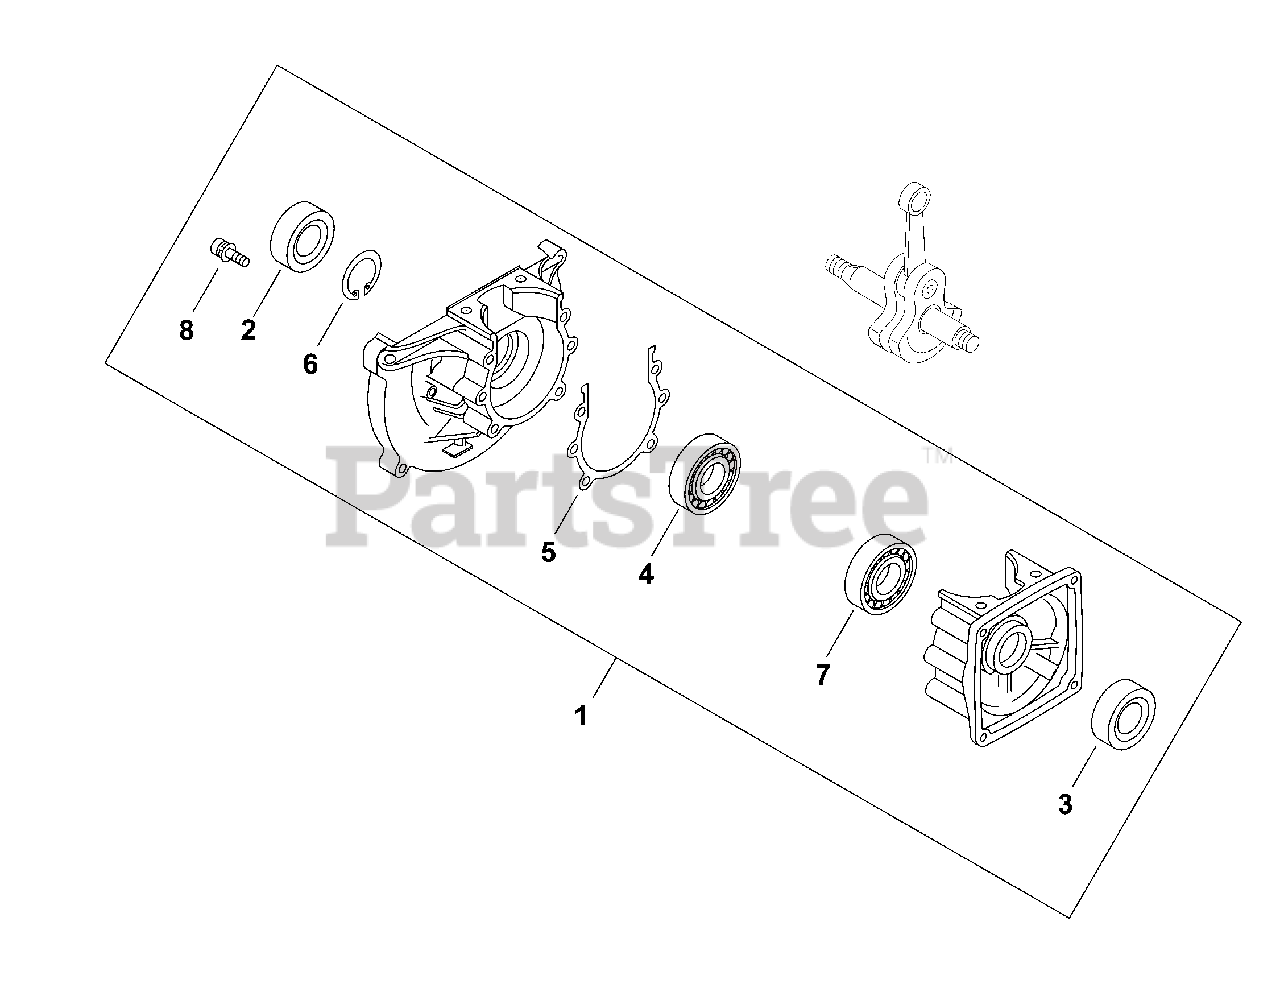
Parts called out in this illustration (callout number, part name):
1	CRANKCASE ASSY
2	SEAL, OIL 18
3	SEAL, OIL 12
4	BEARING, BALL 6202
5	GASKET, CRANKCASE
6	RING, SNAP 35
7	BEARING, BALL 6201
8	BOLT 5×30
